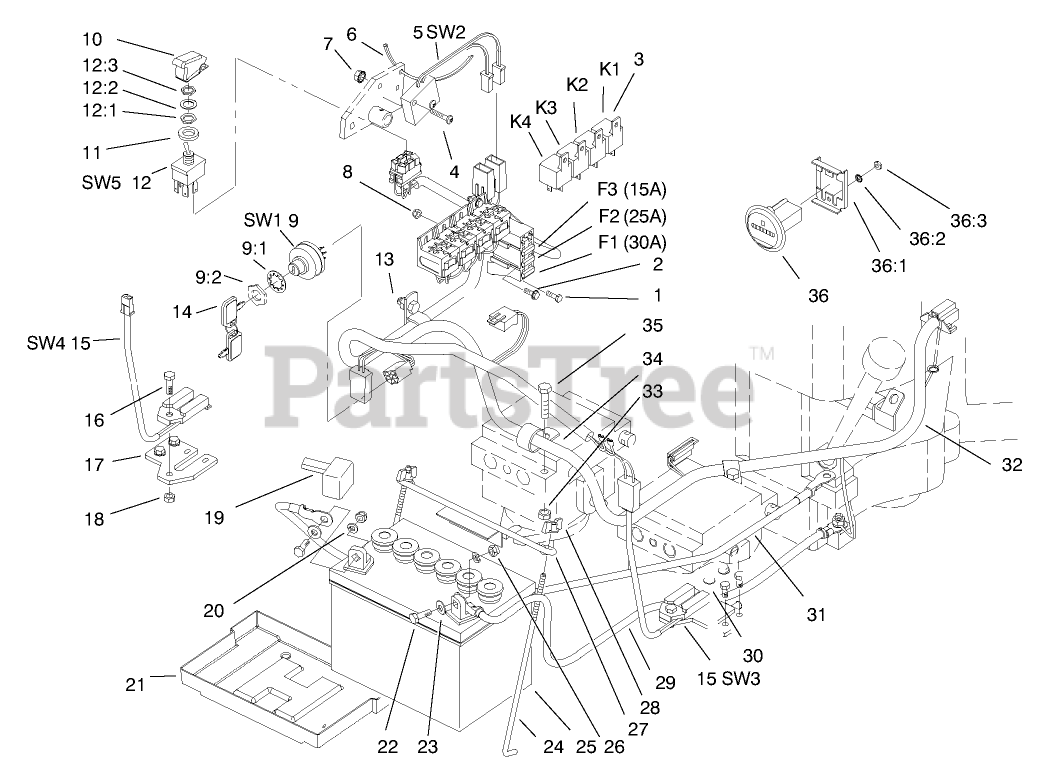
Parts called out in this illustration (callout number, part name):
2	SCREW-SHWH
3	RELAY
4	SCREW-PPH
5	SWITCH-ASS'Y NEUTRAL
6	TIE-CABLE
7	NUT-KEPS
8	NUT-LOCK, NI
9	IGNITION SWITCH ASM
9:2	WASHER-LOCK
10	COVER-PTO SWITCH
11	Spacer
12	SWITCH-TOGGLE, SEALED
12:1	NUT-HEX, SPECIAL
12:2	TAB-WASHER
13	SCREW-HH
14	KEY-IGNITION
15	Switch ASM
16	SCREW-HH
17	PLATE - SWITCH MOUNT
18	NUT-LOCK, NI
19	Boot
20	WASHER-LOCK
21	TRAY-BATTERY
22	SCREW-HH
23	WASHER-FLAT
24	RETAINER-BATTERY
25	Battery
26	NUT-LOCK, NI
27	HOLDDOWN-BATTERY
28	NUT-WING
29	WIRE-GROUND, BATTERY
30	SCREW-HWH
31	WIRE - BATTERY POSITIVE
32	Harness-Main
33	NUT-LOCK, NI
34	CLAMP-R
35	SCREW-HH
36	Hourmeter
36:1	CLAMP-HOUR METER
36:2	WASHER-LOCK
36:3	NUT-HEX
